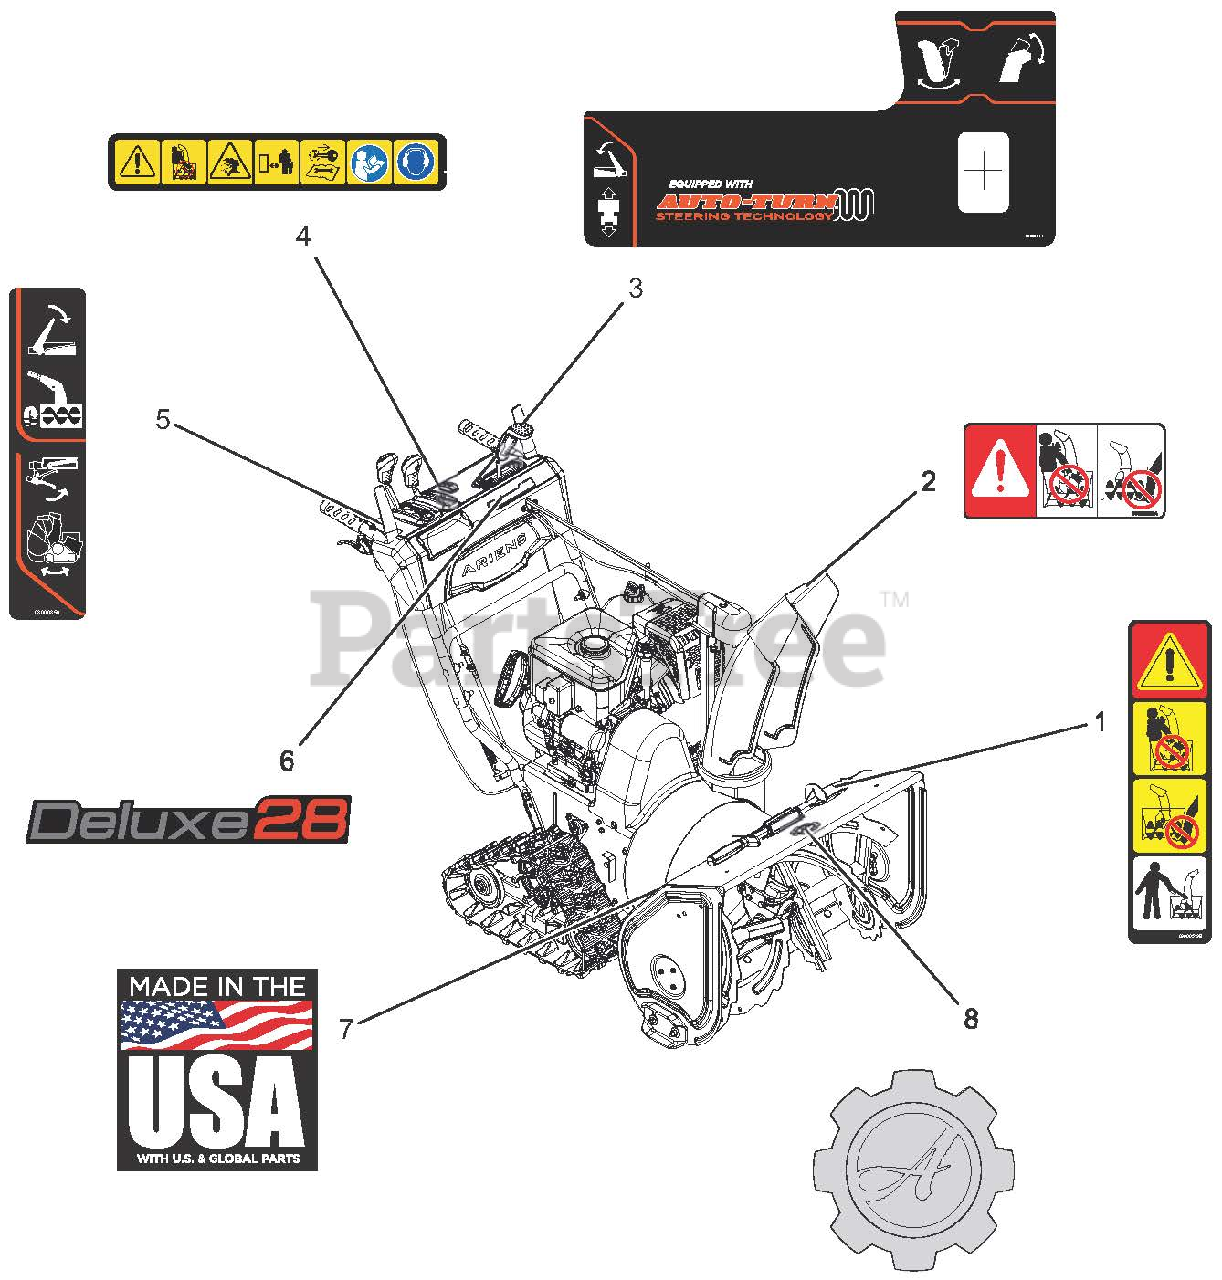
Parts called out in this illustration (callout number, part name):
1	DECAL, DANGER - ROTATING PARTS
2	DECAL, DANGER
3	DECAL,CONTROL-LG QT2
4	DECAL,DASH - SAFETY
5	DECAL,CONTROL-RH TRACK
6	DECAL, DASH - DELUXE 28
7	DECAL, MADE IN USA
8	DECAL, ARIENS-GEAR BADGE
